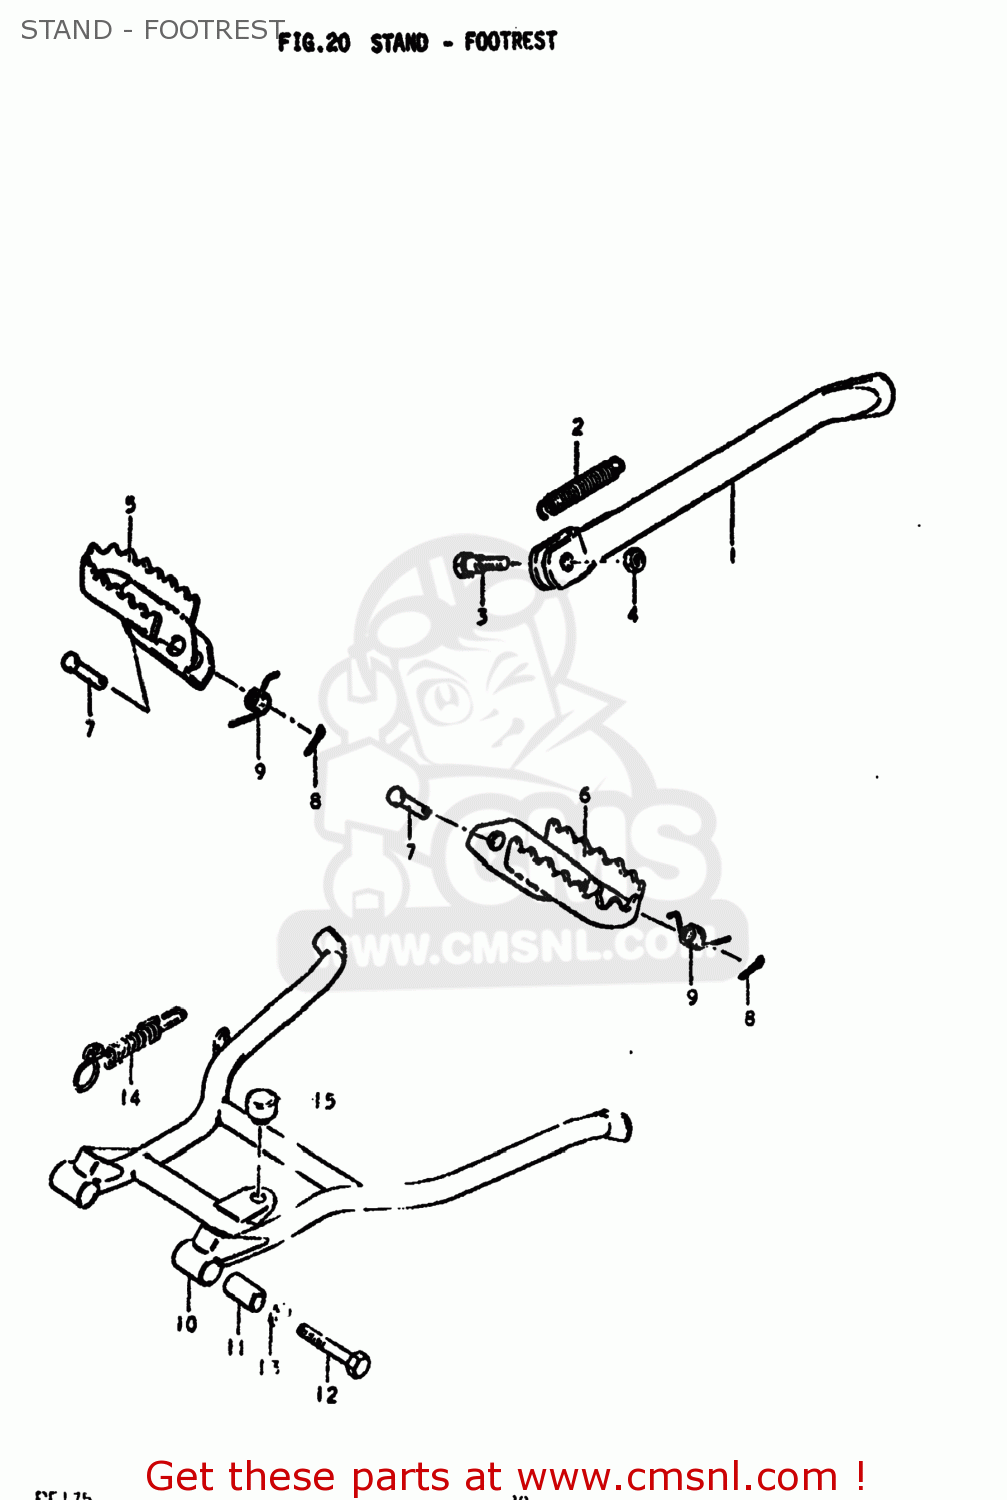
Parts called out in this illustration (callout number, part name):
1	STAND,SIDE
2	SPRING
3	BOLT(10X30)
4	NUT
5	FOOTREST,FR,R
6	FOOTREST,FR,L
7	PIN
8	PIN 25X20
9	SPRING
10	STAND,CENTER
11	SPACER(10.5X16X30)
12	BOLT (10X50)
13	LOCK WASHER
15	CUSHION(11.5X22X20)
